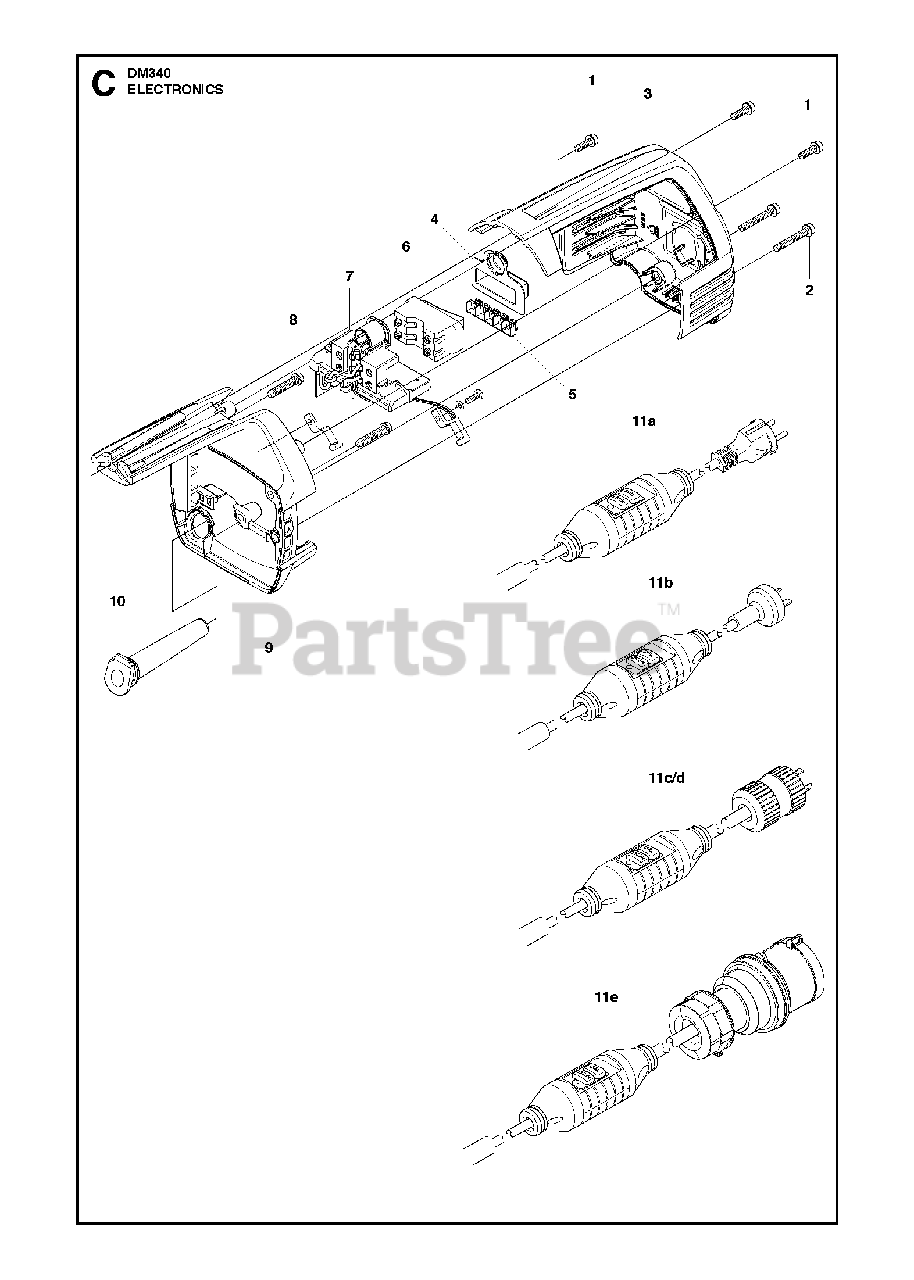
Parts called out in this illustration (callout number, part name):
1	SCREW IHSCFM
2	SCREW IHSCFM
8	SCREW IHSCMValid from 20154700001
8	SCREW IHSCTValid until 20154700001
